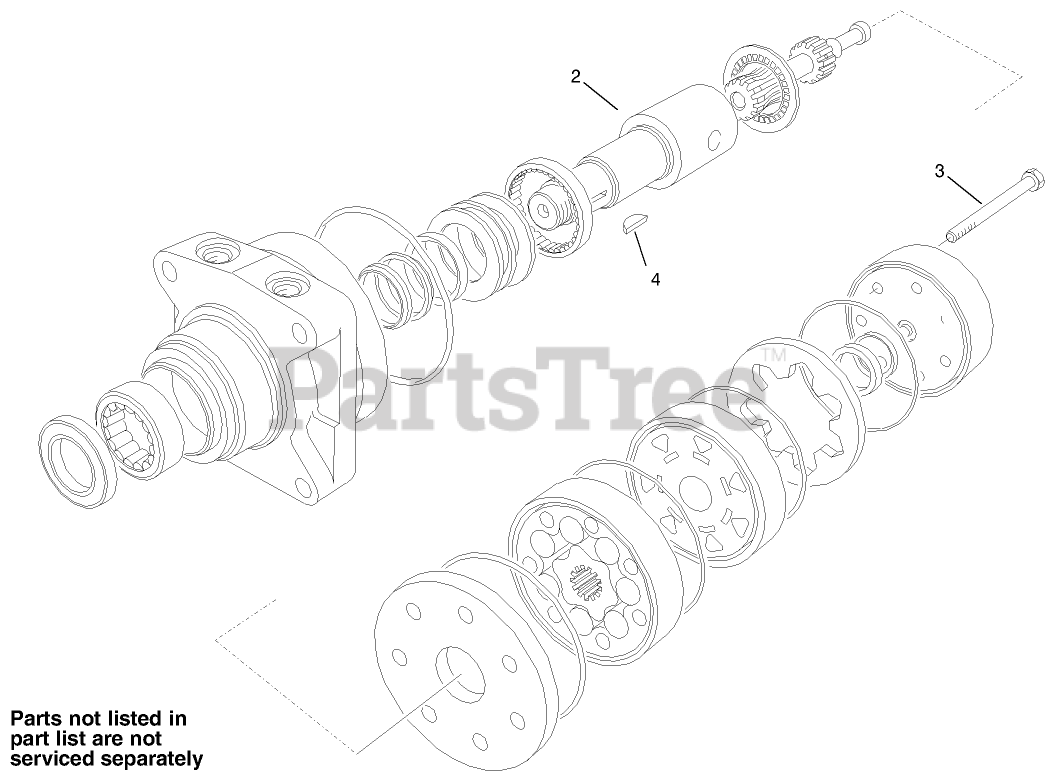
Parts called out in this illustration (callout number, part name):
1	SEAL KIT
2	SHAFT-COUPLING
3	SCREW-CAP, HH
4	KEY-WOODRUFF
